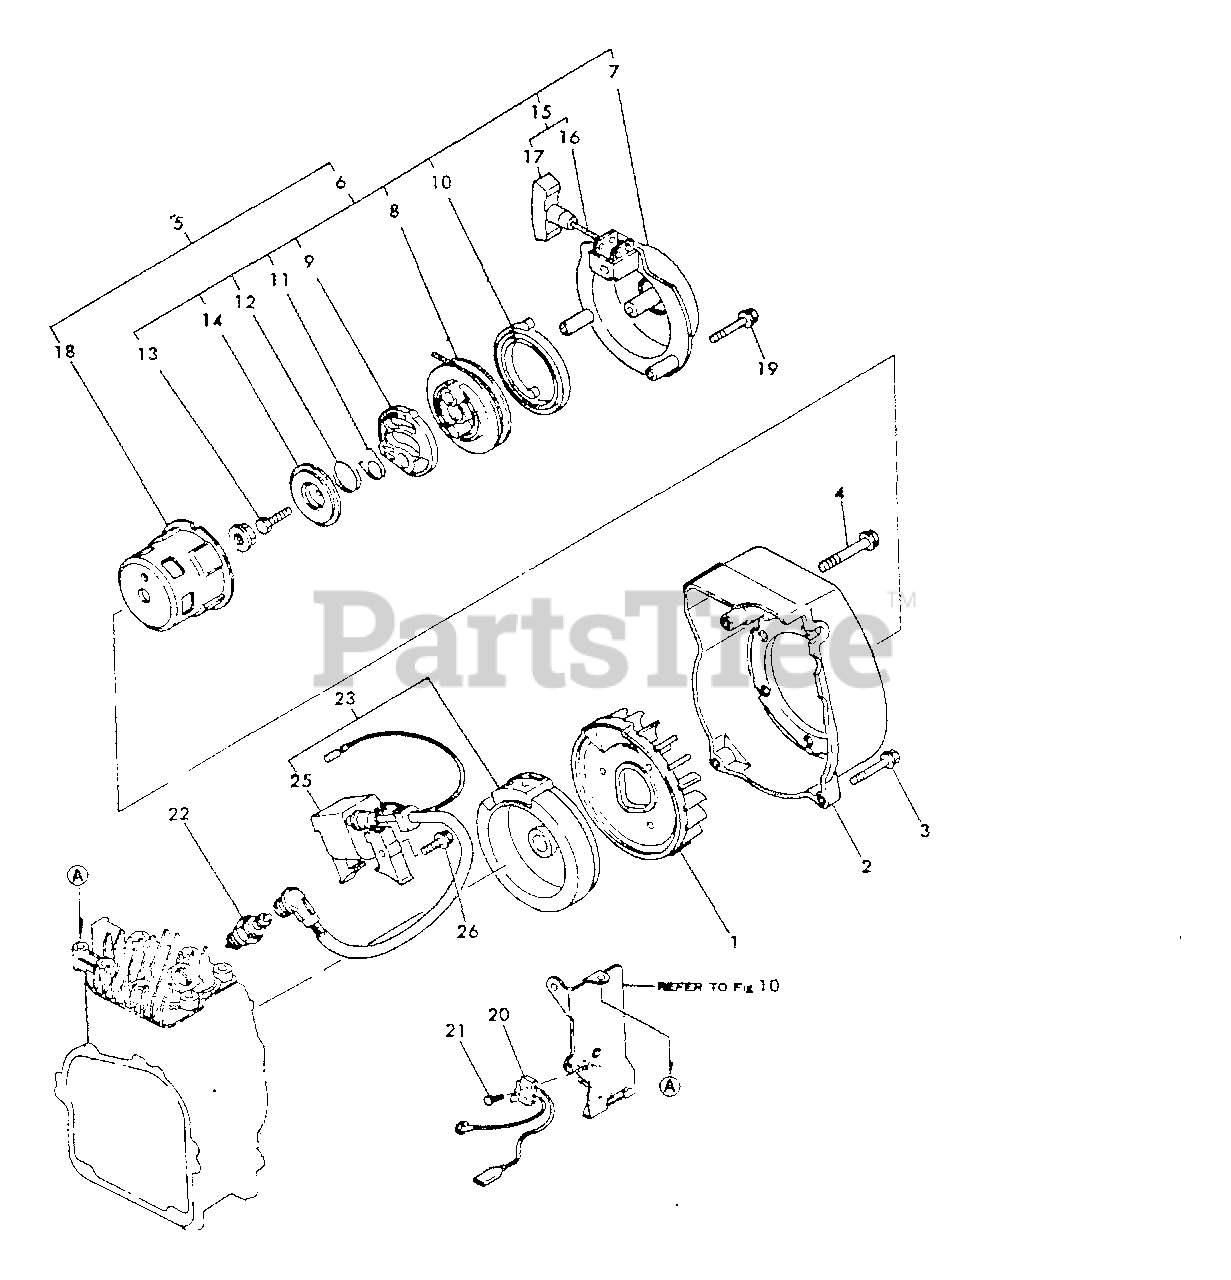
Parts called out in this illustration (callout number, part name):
1	FAN
2	COVER, FAN
3	BOLT - 6X25
4	BOLT - 6X40
5	STARTER ASSY
6	STARTER ASSY
7	STARTER CASE ASSY
8	PULLEY
9	RATCHET
10	SPRING
11	SPRING, RETURN
12	SPRING, FRICTION
13	BOLT
14	PLATE, FRICTION
15	STARTER ROPE ASSY
16	ROPE, STARTER
17	KNOB, STARTER
18	PULLEY, STARTER
19	BOLT - 6X35 -- PLATED
20	IGNITION SWITCH ASSY
21	SCREW - 2X10 -- TAPPING
22	SPARK PLUG -- BPM-8Y
23	FLYWHEEL MAGNETO
25	IGNITER
26	BOLT - 6X20
